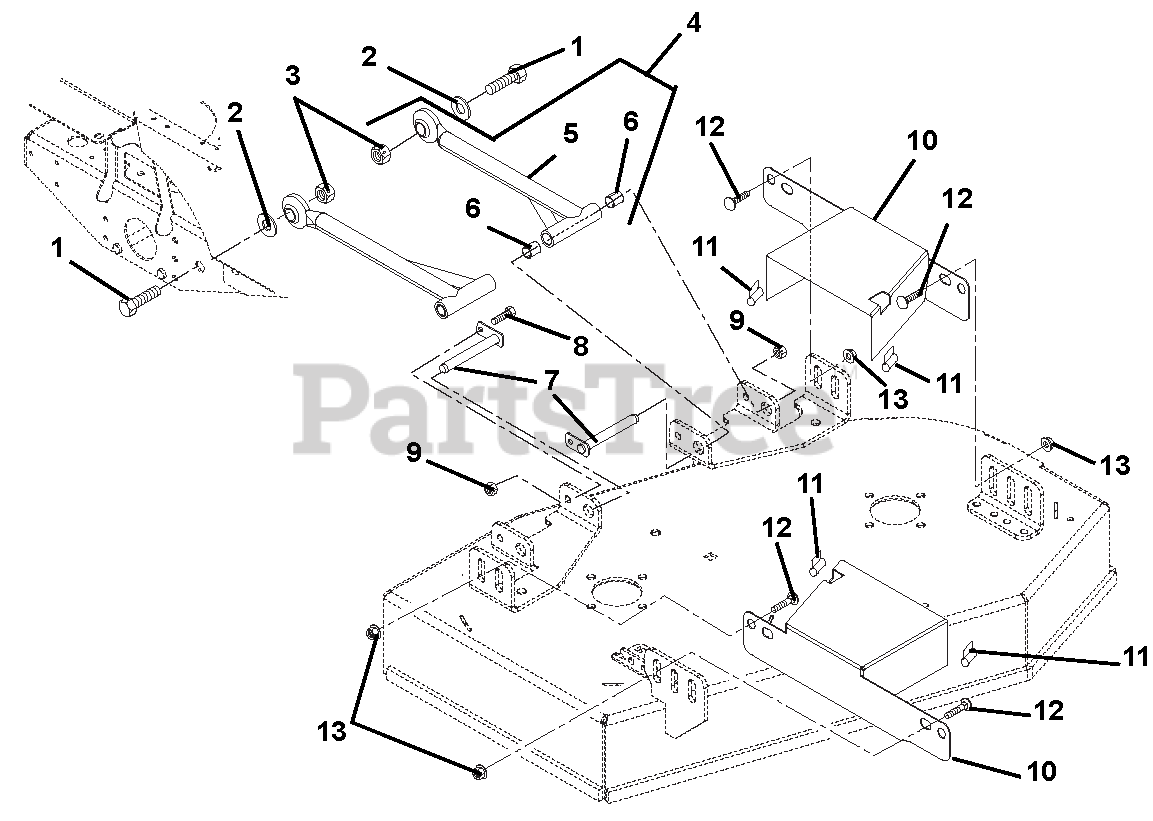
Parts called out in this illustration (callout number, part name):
1	BLT-HEX .875-9X3.00 GR5 YZ
2	BSHG-SLV .882X1.250X.531
3	NUT-LK-CTR .875-9 YWZC
4	ASSY, MOWER MOUNTING
5	MOWER MTG ARM - BLACK
6	BRG, .750 X .875 X 1.000
7	WELDMENT, MOWER MTG. PIN
8	BLT-HEX .38-16X.875 GR5 YWZC
9	@NUT-LK-NYL-FLG .38-16 YWZC
10	GUARD, 34" BELT
11	SEAL, TRIM-LOK BULK .06 BBL 1'
12	@BLT-RDHDSQNK .50-13X1.00 G5YZ
13	@NUT-LK-NYL-FLG .50-13 YWZC
